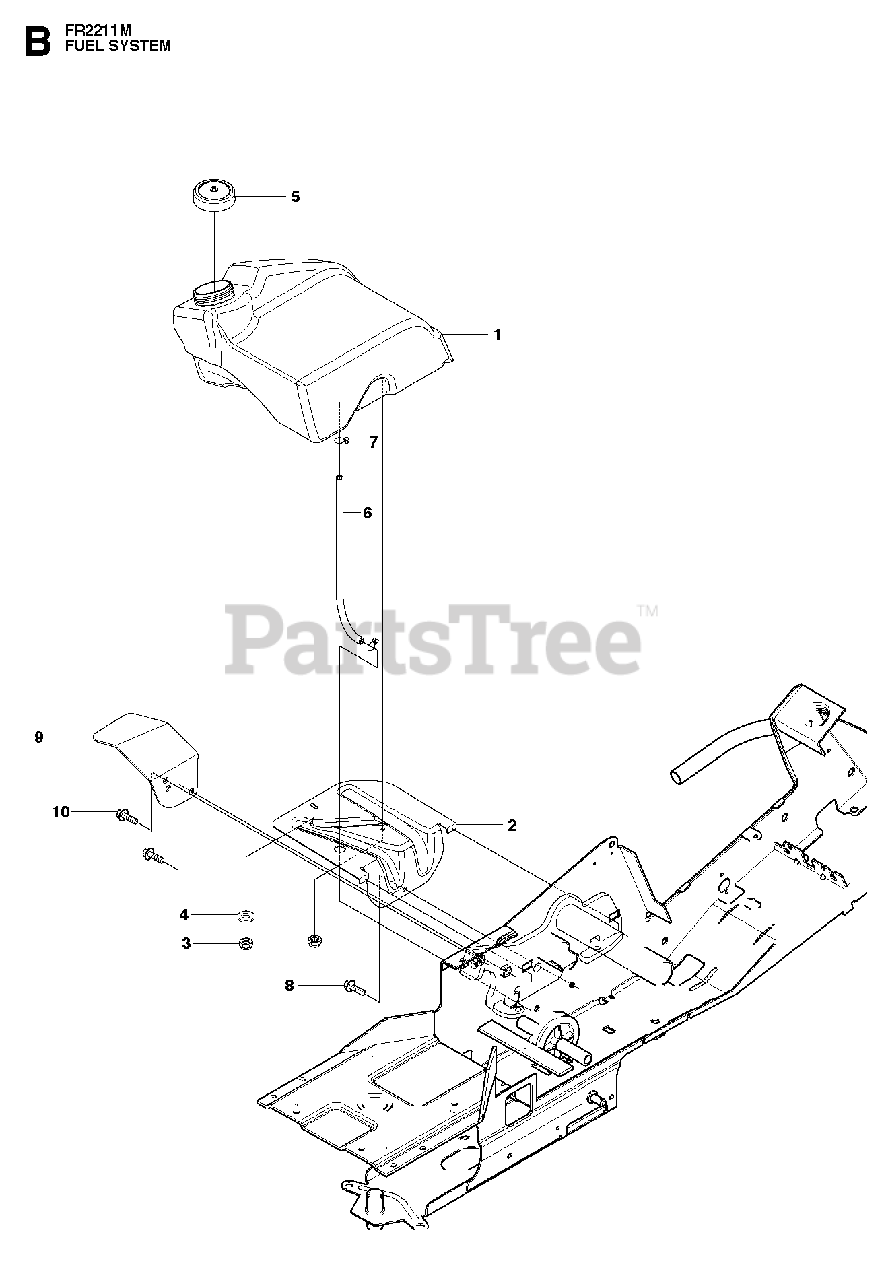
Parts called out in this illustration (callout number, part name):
3	LOCKNUT M6
4	WASHER
10	SCREW M10X25
